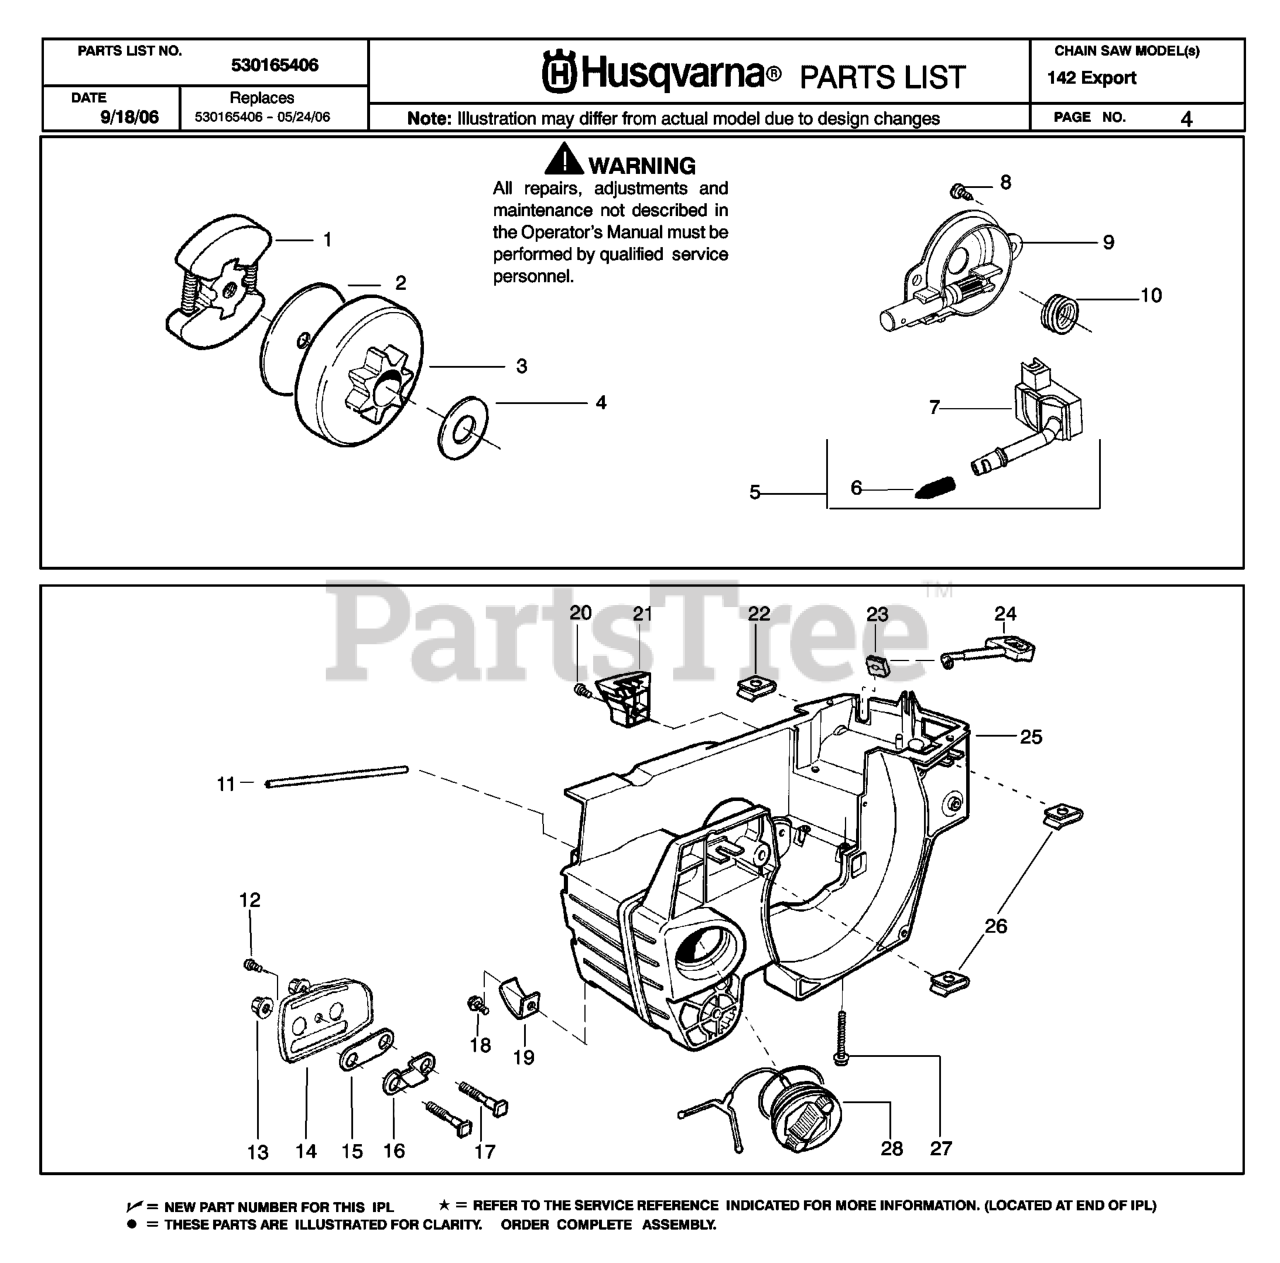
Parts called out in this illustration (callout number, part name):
1	CLUTCH ASSEMBLY
2	FRICTION DISC,CLUTCH 36/41
3	ASSY CLUTCH DRUM .325"
3	CLUTCH DRUM ASSY
4	THRUST WASHER
5	OIL PICKUP
6	SCREEN/FILTER
9	OILER ASS'Y 36/41
10	OILER GEAR 36/41
15	OIL TANK GASKET
16	PLATE,BAR MOUNT
17	BAR BOLT 36/41
19	CHAIN CATCHER 36/41
21	LIMITER COVER
23	CHOKE GUIDE 36/41
24	CHOKE 36/41
25	KIT ASSY CHASSIS
27	SCREW M5-0.8X35M TAP
